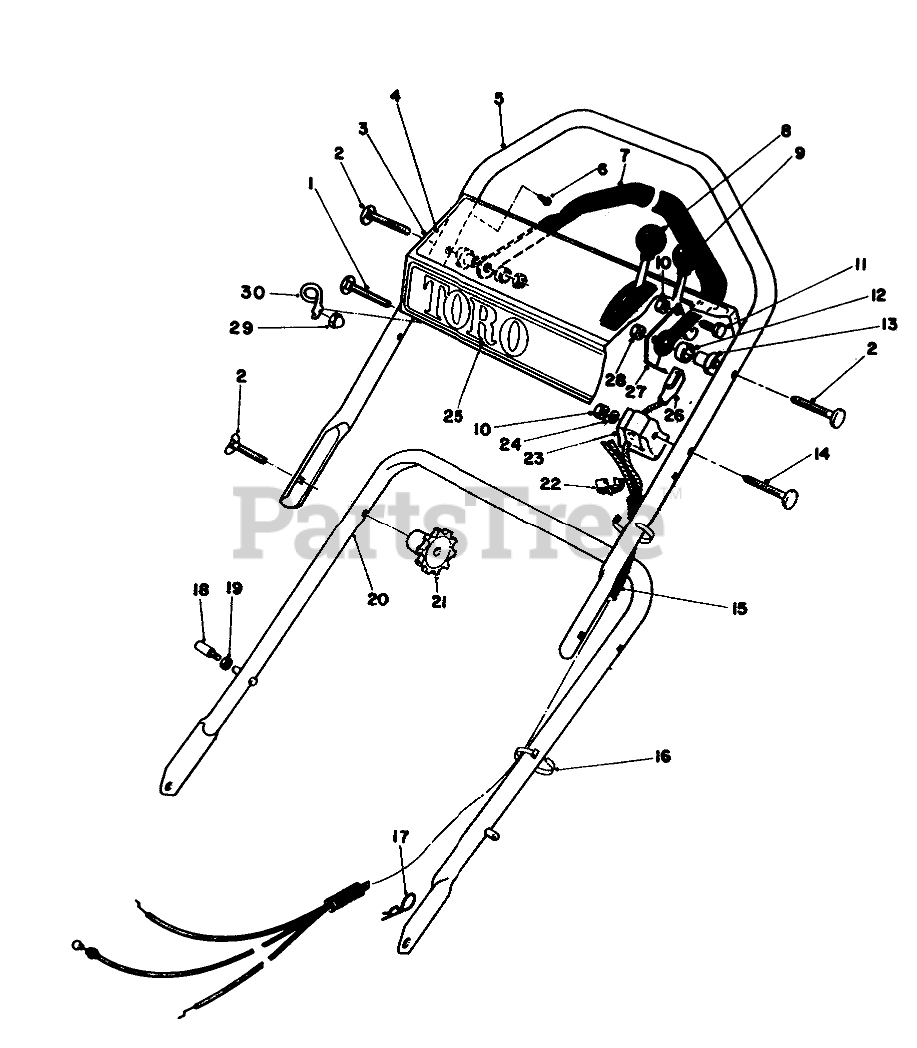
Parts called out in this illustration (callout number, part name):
1	HANDLE SCREW
2	5/16-18 X 2 HNDLE SCREW
3	Panel-Control (Incl. Ref. #4)
4	Decal-Instructions
5	Handle-Upper
6	SCREW-HWHTF
7	Bar-Control
8	SERVICE TRACT. CONTROL
9	THROTTLE CONT-SERVICE
10	NUT-LOCK, NI
11	SCREW-HH
12	SPACER-NYLON
13	SPACER-SUPPORT
14	SCREW-HANDLE
15	CONT. CABLE COVER
16	TIE-CABLE
17	PIN-COTTER, HAIR
18	CHOKE DECAL
19	NUT-LOCK, NI
20	LOWER HANDLE ASM
22	FITTING-RING
23	SUPPORT-CABLE
24	WASHER-FLAT
25	Decal-Toro
26	BRAKE CABLE
27	Lever-Control
28	NUT-LOCK, NI
29	NUT-CAP
30	Guide
